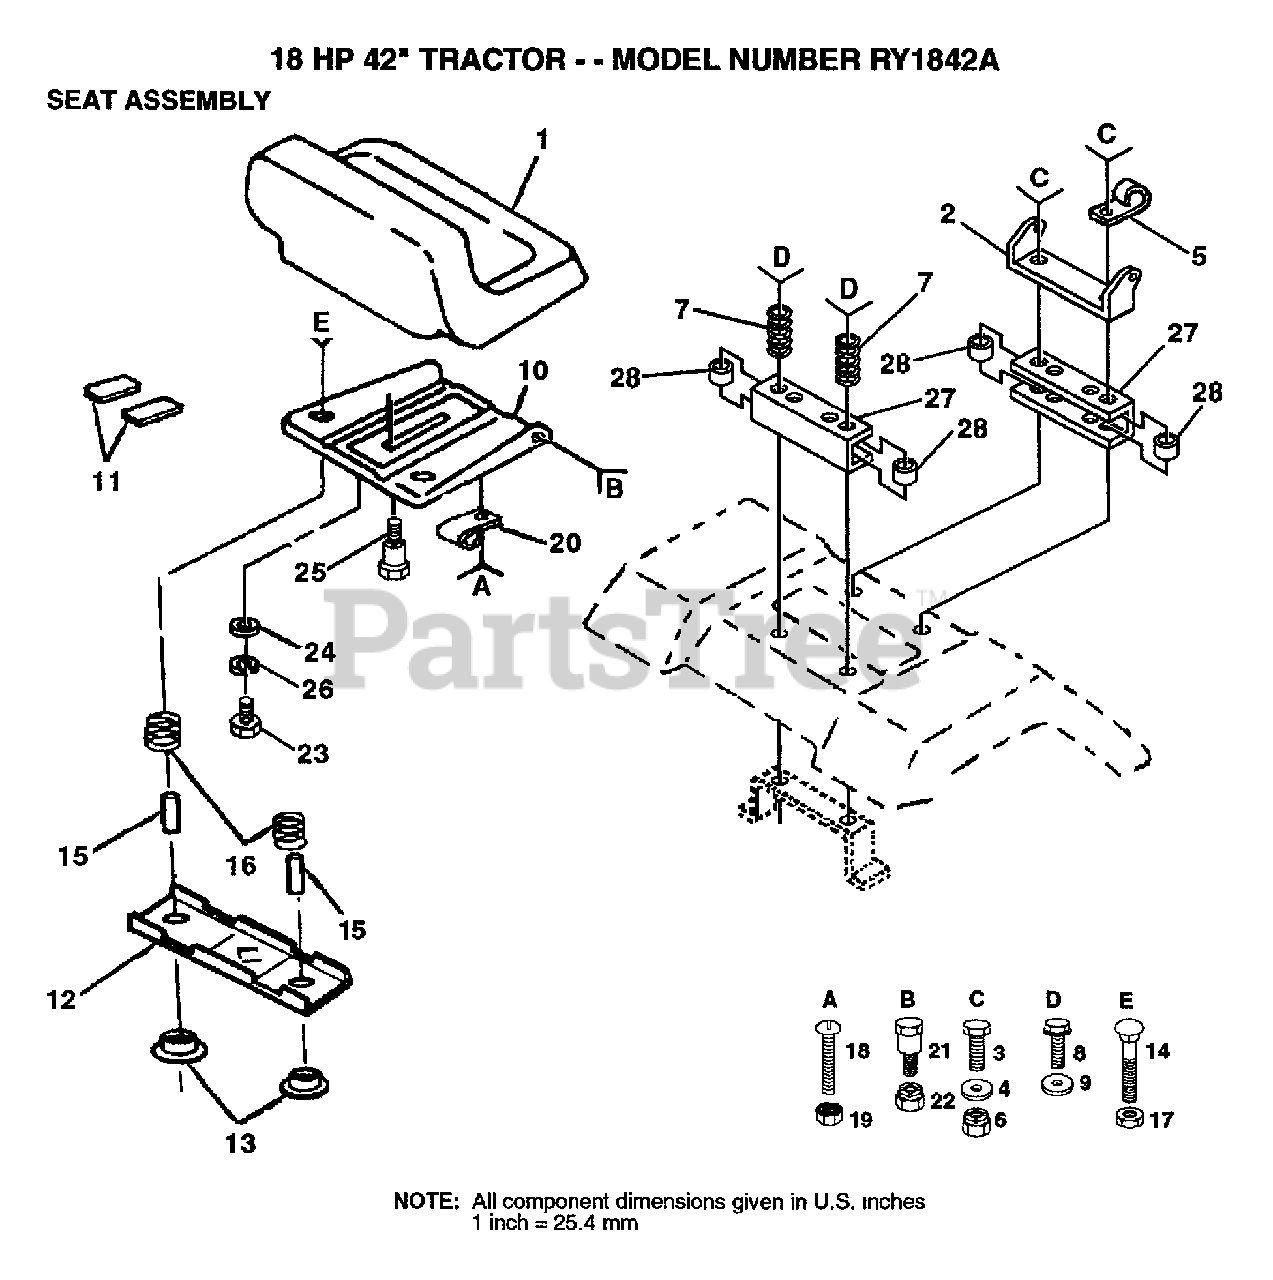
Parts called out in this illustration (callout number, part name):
3	BOLT
4	WASHER
5	CLIP T
7	SPRING COMPRESSIO
8	SCREW
9	WASHER
11	STRIP FORM
12	BRKT SWITCH
13	BUSHING
15	SPACER SPLIT
16	SPRING
19	"NUT,KEPS"
23	BOLT
24	WASHER
25	"BOLT,SHOULDER"
26	LOCKWASHER
27	SEAT SPACER
28	SPLIT SPACER
